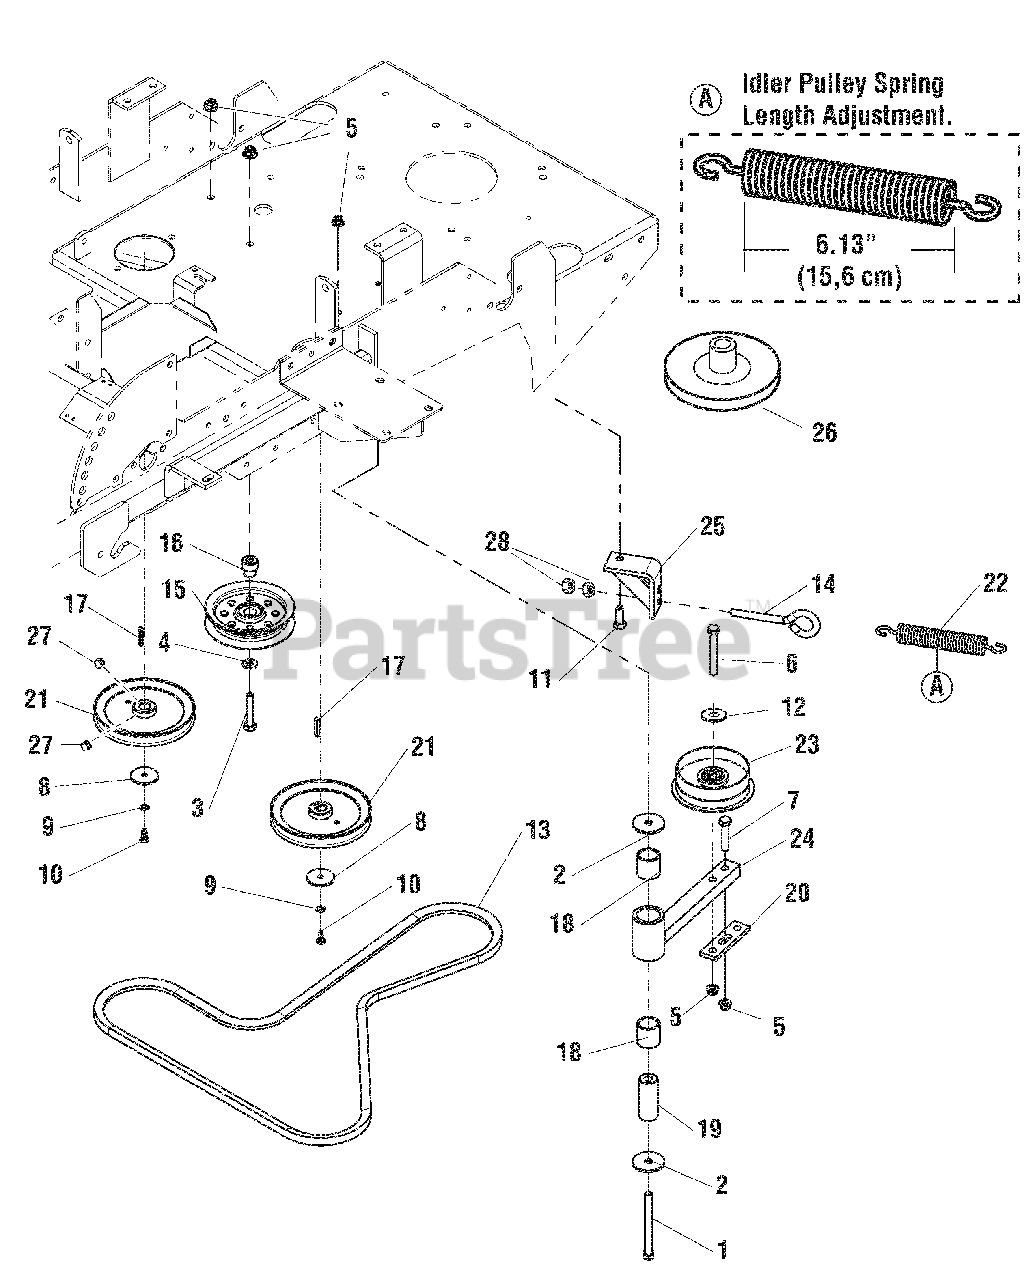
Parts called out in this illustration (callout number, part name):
1	BOLT, 3/8-16 X 4" GD5 CZ
2	WASHER, .41 X 1.75 X .14
3	BOLT, 3/8-16 X 2, GD5, CZ
4	WASHER, 3/8 SAE
5	NUT, 3/8-16 HEX NYLOCK FLANGE
6	BOLT, 3/8-16 X 2-1/2" GD5 CZ
7	BOLT, 3/8-16 X 1-3/4" GD5 CZ
8	WASHER, .265 X 1.50 X .109, YZ
9	WASHER, 1/4 LOCK
10	CAPSCREW, HEX HEAD M6-1.0X 14MM
11	BOLT, 3/8-16 X 1" GD5 CZ
12	WASHER, 3/8 GD.9 FLAT
13	BELT, HA-SEC, 72.4EL, ARAMID, WRPD
14	EYEBOLT, 3/8-16 X 4, 2.13THRD, .75EYE, C
15	PULLEY, IDLER, 4.06OD, .669ID, .75W STL
16	SPACER, HYDRO PULLEY
17	KEY, 5MM SQ. W/ RADIUS
18	BUSHING, BRASS, 1.25X1X1.25
19	SPACER, .39 X 1.000 X 2.55, SS
20	PLATE, ANCHOR, SPRING
21	PULLEY, PUMP DRIVE
22	SPRING, EXTENSION, 1.00
23	PULLEY, IDLER, SINGLE FLANGE
24	WELD, ARM, PUMP DRIVE IDLER
25	WELD, ANCHOR EYEBOLT
26	PULLEY, CRANKSHAFT
27	SET SCREW, 5/16-24 X 3/8, KNURL, W/PATCH
28	NUT, 3/8-16 HEX
